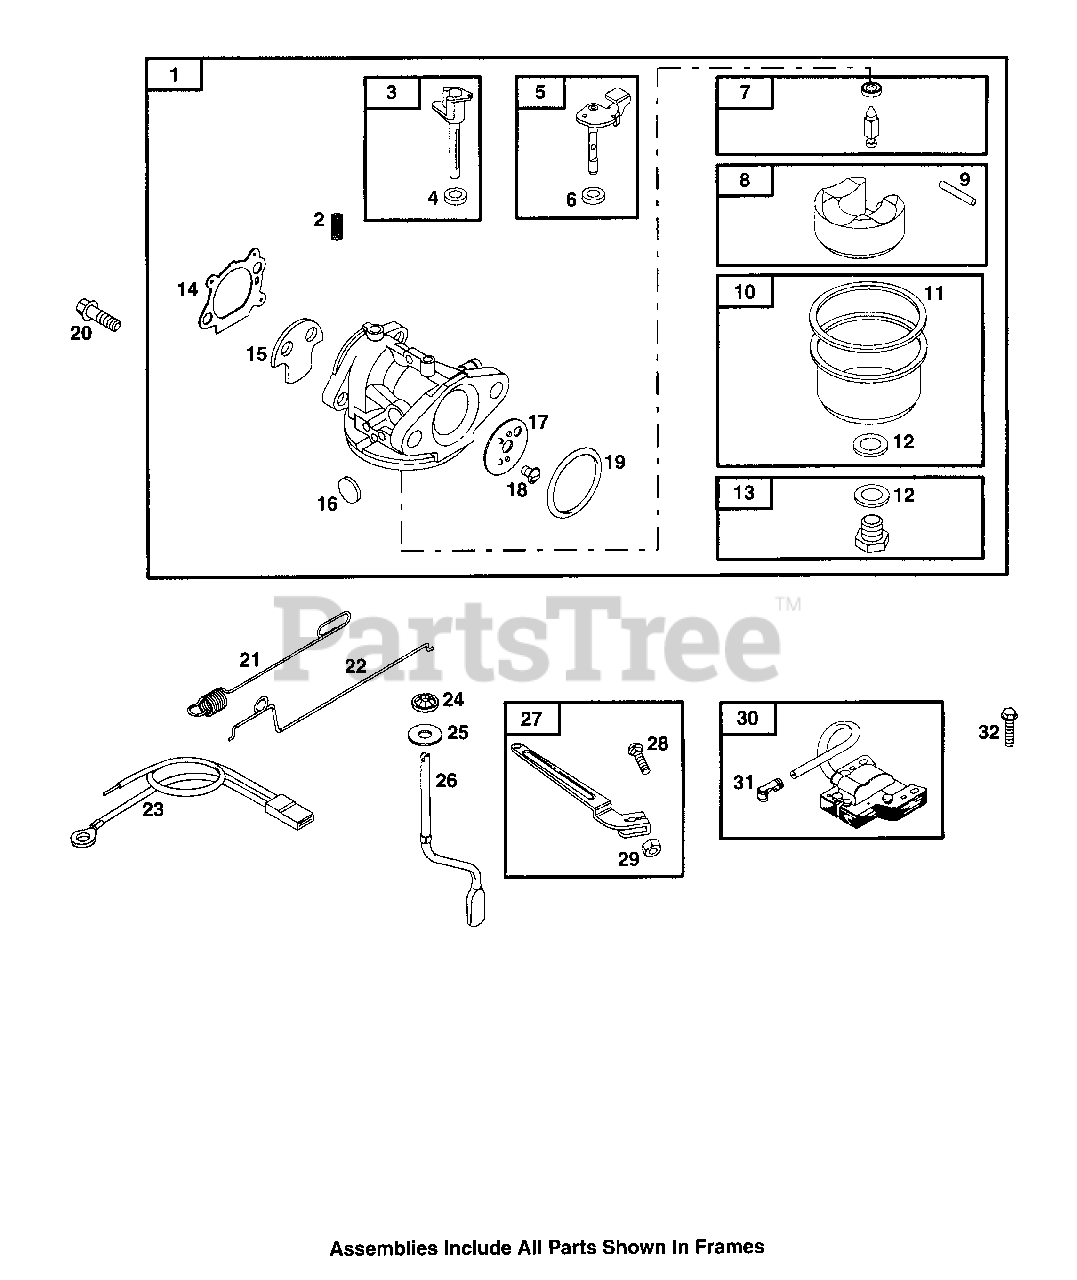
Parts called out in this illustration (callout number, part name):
1	Carburetor
2	Detent Spring
3	Choke Shaft
4	Choke Shaft Seal
5	Throttle Shaft
6	Throttle Shaft Seal
7	Needle/Seat Kit
8	Carburetor Float
9	Float Hinge Pin
10	Float Bowl
11	Float Bowl Gasket
12	Sealing Washer
13	Main Jet (Standard)
14	Air Cleaner Gasket
15	Choke Valve
16	Welch Plug
17	Throttle Valve
18	Screw (Throttle Valve)
19	O-Ring Seal (Intake Manifold)
20	Screw (Carburetor)
21	Governor Spring
22	Mechanical Governor Link
24	Retainer Governor Shaft
25	Washer (Governor Crank)
26	Governor Crank
27	Governor Control Lever
28	Bolt (Governor Control Lever)
29	Nut (Governor Control Lever)
30	Magneto Armature
31	Sparkplug Terminal
32	Screw (Magneto Armature)
